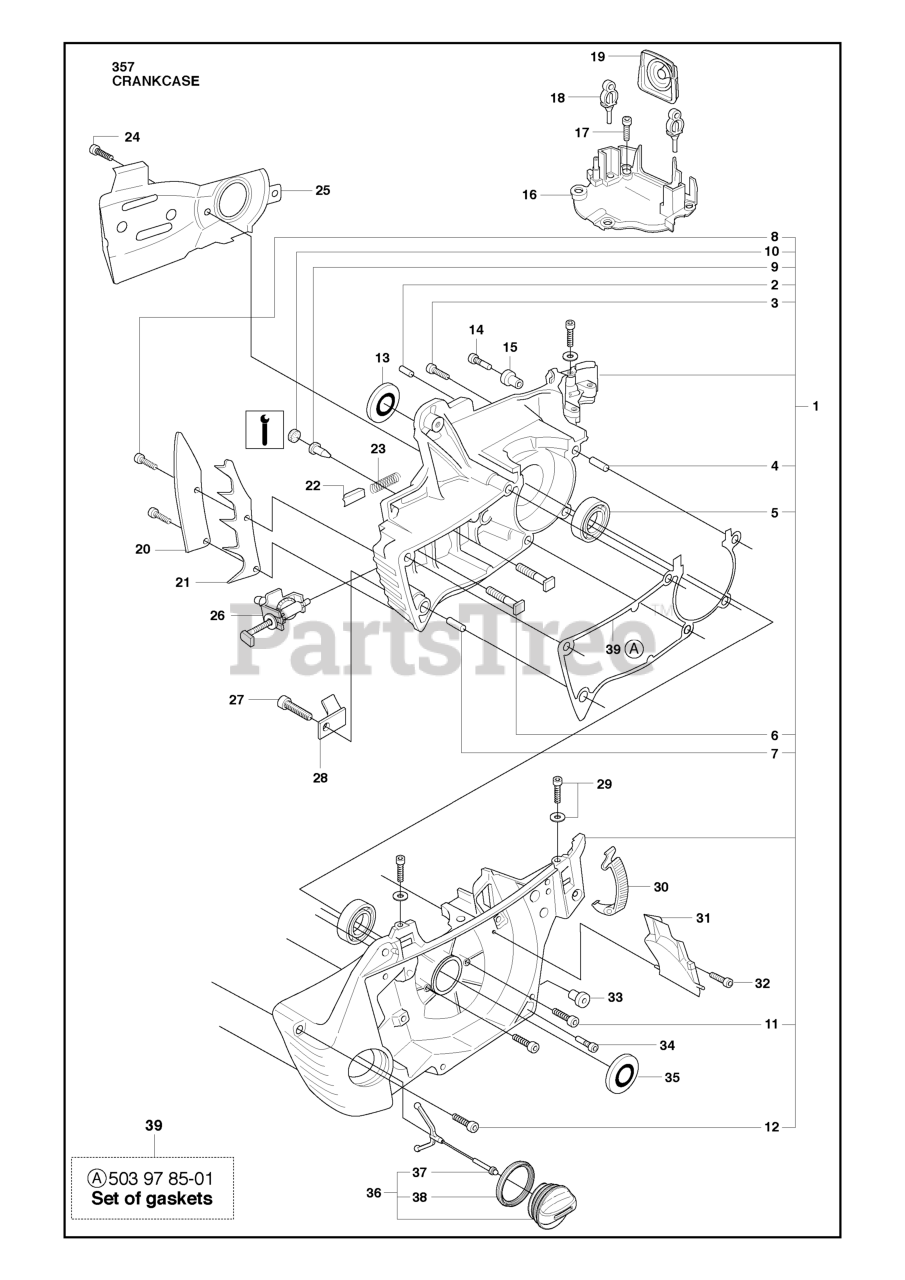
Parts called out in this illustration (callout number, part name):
5	BALL BEARING-6202-C3 SKF
9	VALVE-CHECK (DUCKBILL)
10	PLUG
15	MOVEMENT LIMITER
18	SUPPORT
21	FELLING DOG
23	LOCK SPRING
26	CHAIN TENSIONER
28	CHAIN CATCHER
30	BUCKLE ORANGE
33	MOVEMENT LIMITER
36	TANK CAP
38	SEALING
39	GASKET SET
